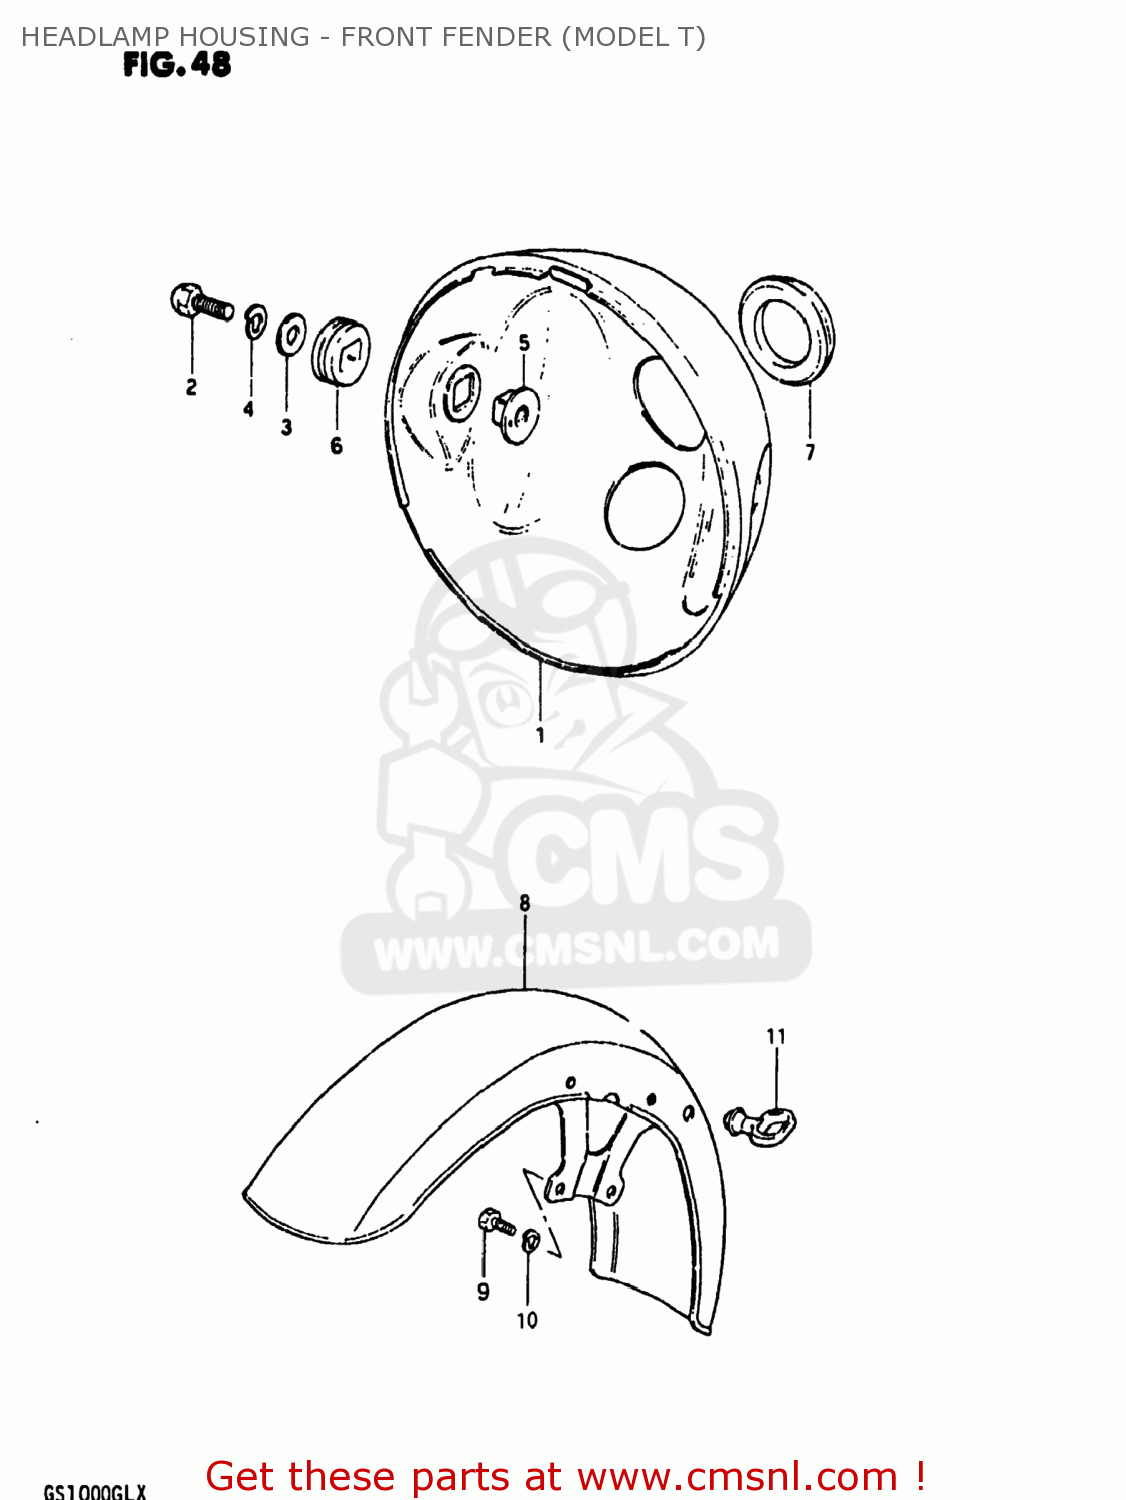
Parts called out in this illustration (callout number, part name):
1	HOUSING,HEADLAMP
2	BOLT
3	WASHER
4	LOCK WASHER
5	SPACER,HEADLAMP HOUSING
6	CUSHION,HEADLAMP HOUSING
7	GROMMET,HEADLAMP HOUSING
8	FENDER,FRONT
9	BOLT
10	LOCK WASHER
11	GUIDE,CABLE
